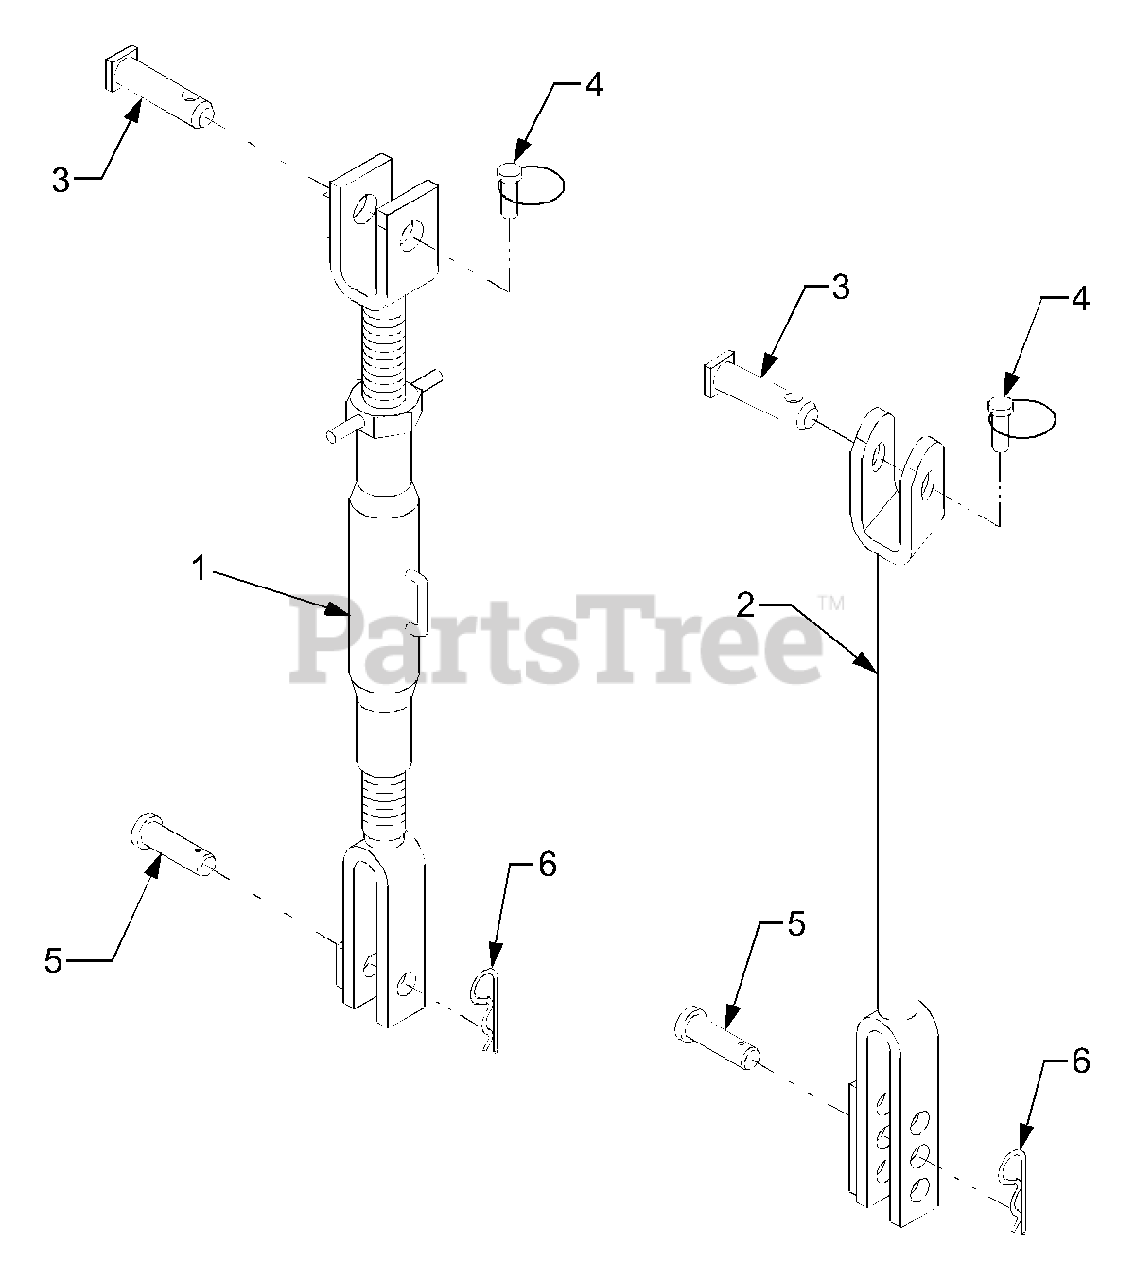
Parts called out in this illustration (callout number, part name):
1	Lift Rod Ass'y (RH)
2	Lift Rod Ass'y (LH)
3	Pin, Lift Rod
